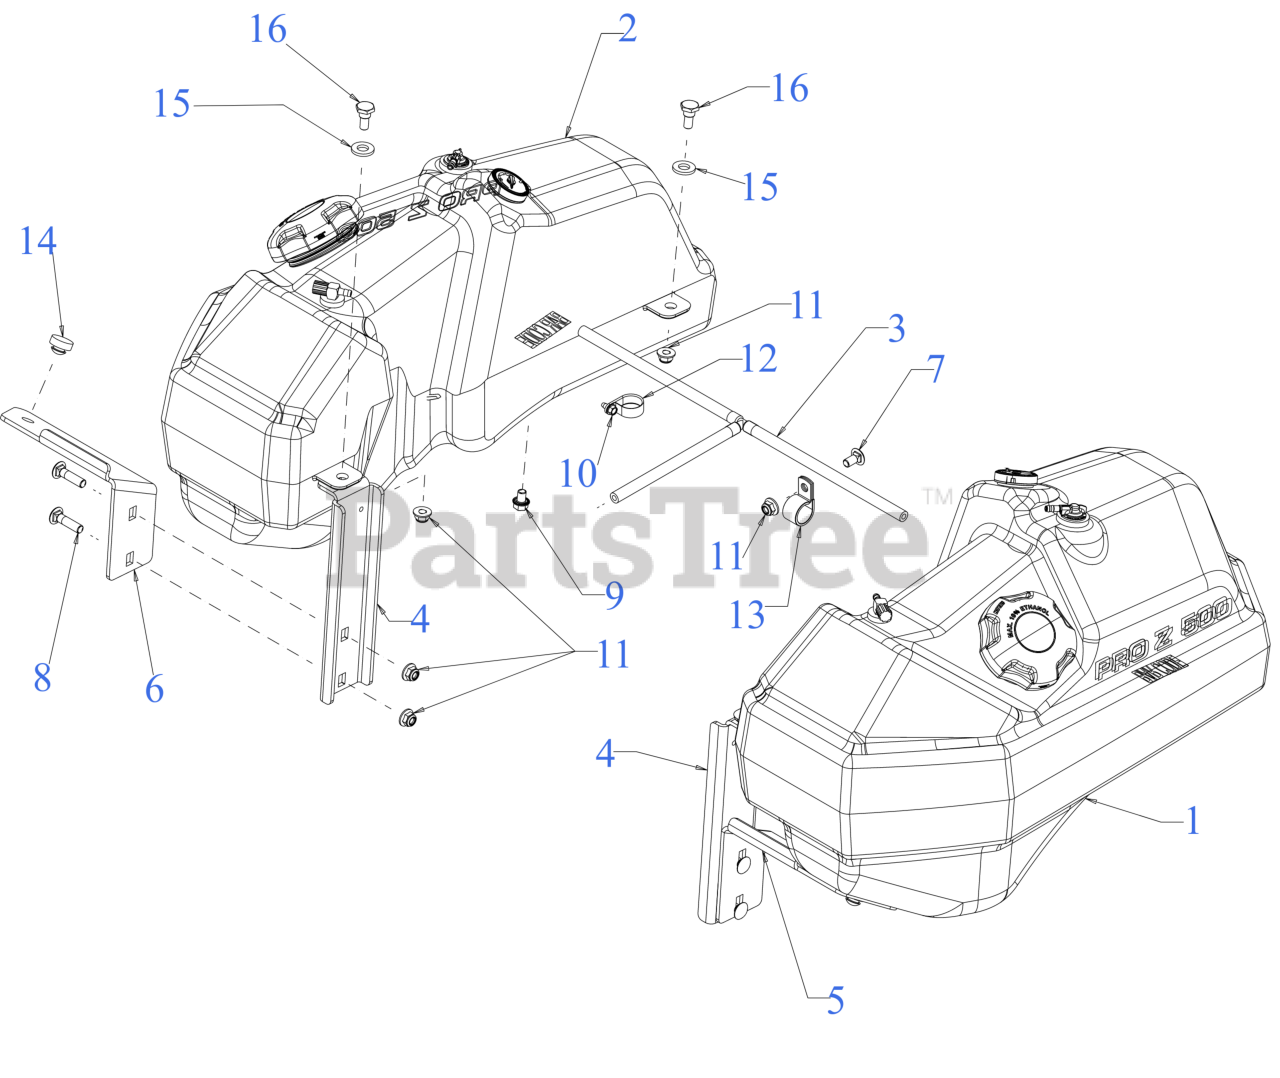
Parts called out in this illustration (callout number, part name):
1	FUEL TANK ASSEMBLY (RH) (7.25 GAL)
2	FUEL TANK ASSEMBLY (LH) (7.25 GAL)
3	FUEL LINE ASSEMBLY
4	FUEL TANK MOUNTING BRACKET
7	CARRIAGE BOLT 3/8-16 x .750 GR5
8	CARRIAGE BOLT 3/8-16 x 1.50
9	SCREW 3/8-16 x .500 GR5
10	SCREW 1/4-20 X.500
12	DRAIN HOSE CLAMP
13	HOSE CLAMP 1.0"
14	RUBBER BUMPER 1.000 x .313
15	FLAT WASHER .510 x 1.000 x .125
16	SHOULDER SCREW .498 DIA x .340
